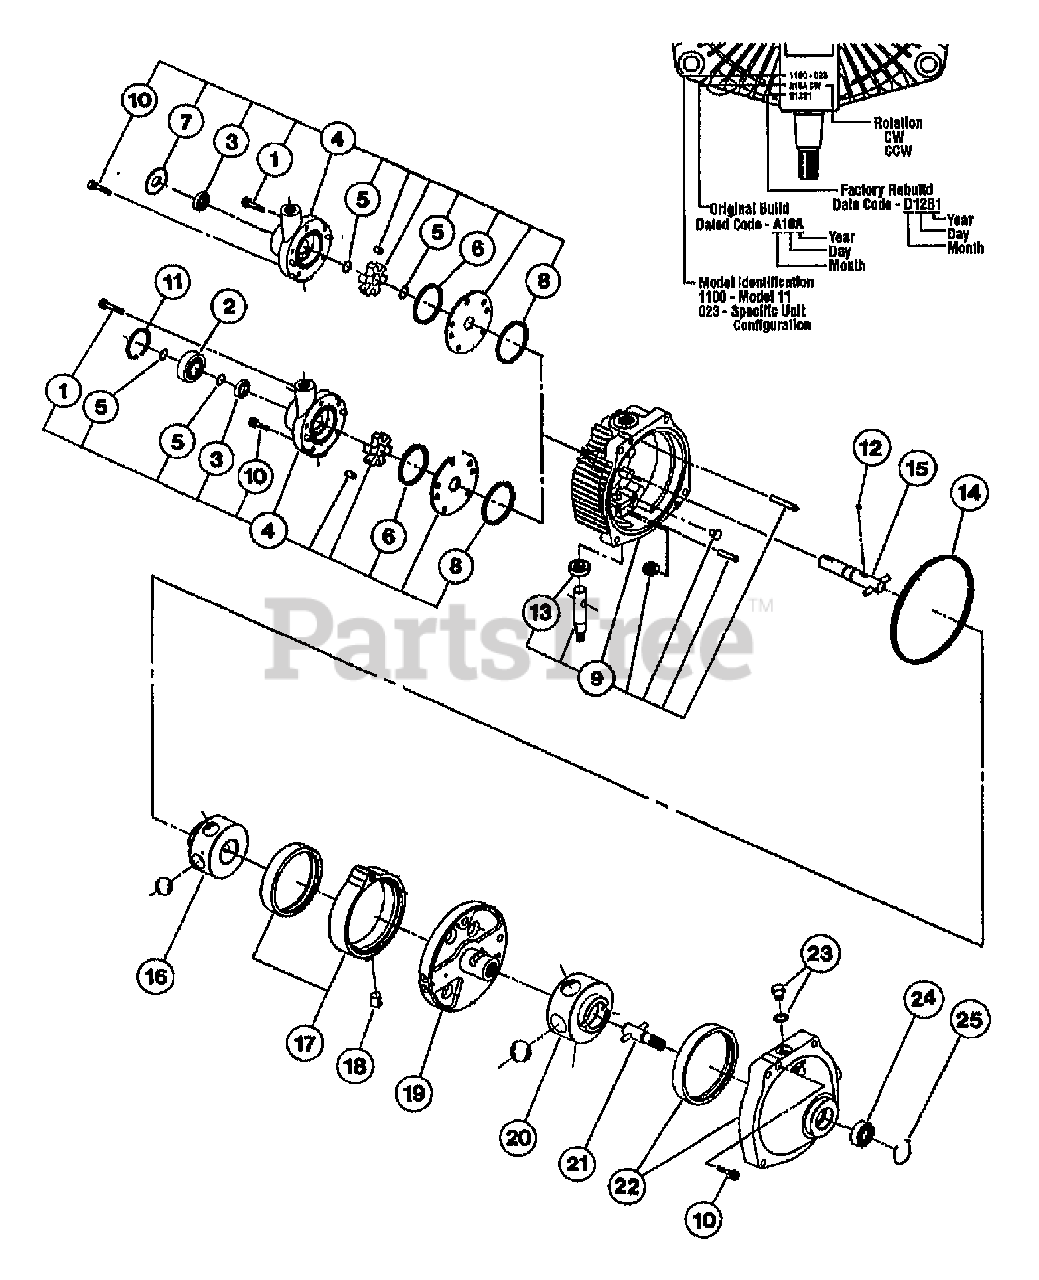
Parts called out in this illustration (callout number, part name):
1	SOCKET HEAD CAPSCREW
3	SEAL-OIL
4	KIT-PUMP CHARGE
5	RING-SNAP
6	RING-SQ SEAL
7	SHIELD-GRASS
8	RING-SQ SEAL
9	ASSM-COVER
10	SOCKET HEAD CAPSCREW
12	PIN-DRIVE
13	SEAL-OIL
14	RING-SQ SEAL
15	SHAFT-INPUT (W/KEY)
16	ASSM-PUMP ROTOR & BALL
17	ASSM-RING CAM
18	RING-CAM INSERT
19	ASSM-PINTLE
20	ASSM-MOTOR ROTOR & BALL
21	SUBASSM-OUTPUT SHAFT
22	ASSM-BODY
23	SUBASSM-O RING PLUG
24	BRG-BALL (OUTPUT)
25	RING-RETAIN
